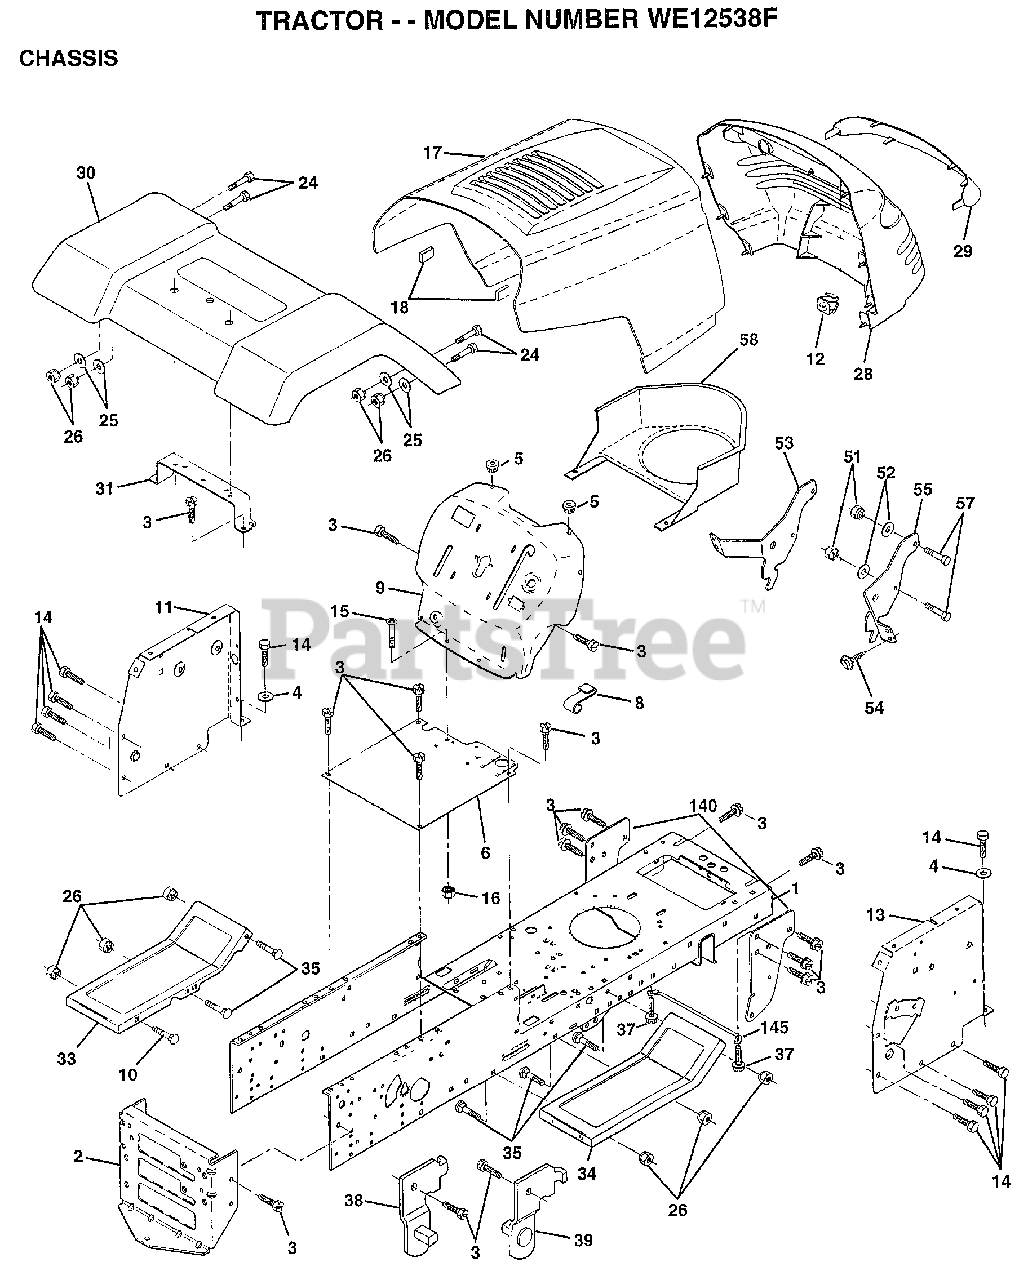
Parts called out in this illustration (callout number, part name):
1	CHASSIS.STAMPING
3	SCREW
4	WASHER
5	BUMPER-HOOD/DASH
6	SADDLE-SILKSCREEN
8	CLIP.RETAINER
9	DASH SILKSCREEN
11	"PANEL-DASH,LH"
12	CLIP.TINNERMAN
14	SCREW LT
15	SCREW
17	HOOD.STEEL.ASSY
24	BOLT
25	WASHER
26	NUT
28	GRILLE-MS428
29	LENS.GRILLE.PRIVATE LABEL
30	FENDER.PNTL.LT.W/O.SHIFT
31	BRKT FENDER
33	FOOTREST.LH.PERF.
34	FOOTREST.RH.PERF.
35	BOLT
37	SCREW LT
38	BRACKET ASM LH
39	BRACKET ASM RH
51	NUT
52	WASHER
53	BRACKET.GRILLE.LH
54	SCREW.HEX.WS.HD
55	BRACKET.GRILLE.RH
58	AIR DUCT
140	BRKT SUSPENSION
145	"ROD POVOT,CHASSIS"
